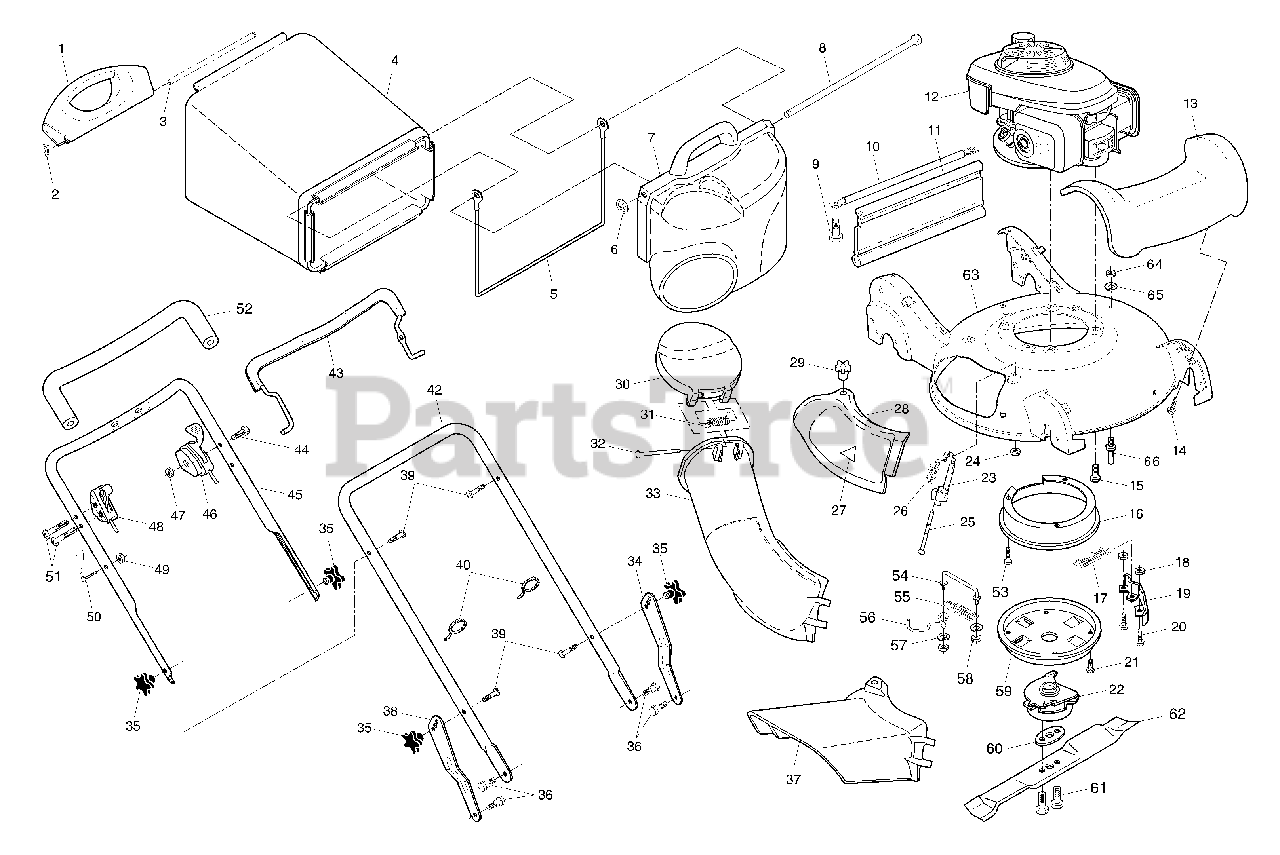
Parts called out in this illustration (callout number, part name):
1	Handle, Grassbag, Rear
2	Hairpin Cotter
3	Rod, Rear Handle, Grassbag
4	Grassbag
5	Frame, Grassbag
7	Door, Grassbag
8	Rod, Pivot
10	Tube, Rear Skirt
11	Skirt, Rear
13	Cover, Front
14	Screw, Hex Washer Head
15	Bolt, Engine Mounting
16	Belt Cover, Upper
18	Nut, Hex
19	Brake, Clutch
20	Bolt, Hex Head
21	Screw
22	Blade Brake / Clutch
23	Mounting Bracket, Mulcher Door
24	Nut, Hex
25	Rod, Hinge
26	Spring, Mulcher Door
27	Decal, Danger
28	Mulcher Door
30	Door, Discharge Chute
31	Spring, Door, Discharge Chute
32	Rod, Door, Discharge Chute
33	Discharge Chute, Plastic
33	Discharge Chute Assembly, Complete
34	Adjustment Bracket, Lower Handle, LH
35	Knob, Star
36	Bolt, Shoulder
37	Deflector, Discharge
38	Adjustment Bracket, Lower Handle, RH
39	Bolt, Handle
40	Wire Tie
42	Handle Assembly, Lower
43	Bail, Control
45	Handle Assembly, Upper
46	Blade Brake Control
48	Throttle Control
50	Rope Guide
51	Screw
52	Grip, Foam
53	Bolt, Engine
54	Link, Torque
56	Belt Keeper
57	Washer, Lock
59	Belt Cover, Lower
60	Spacer, Blade
61	Bolt, Hex Head
62	Blade, 21"
63	Kit, Housing
64	Nut, Hex 3/8-16
65	Washer, Lock
66	Stud, Belt Guide
